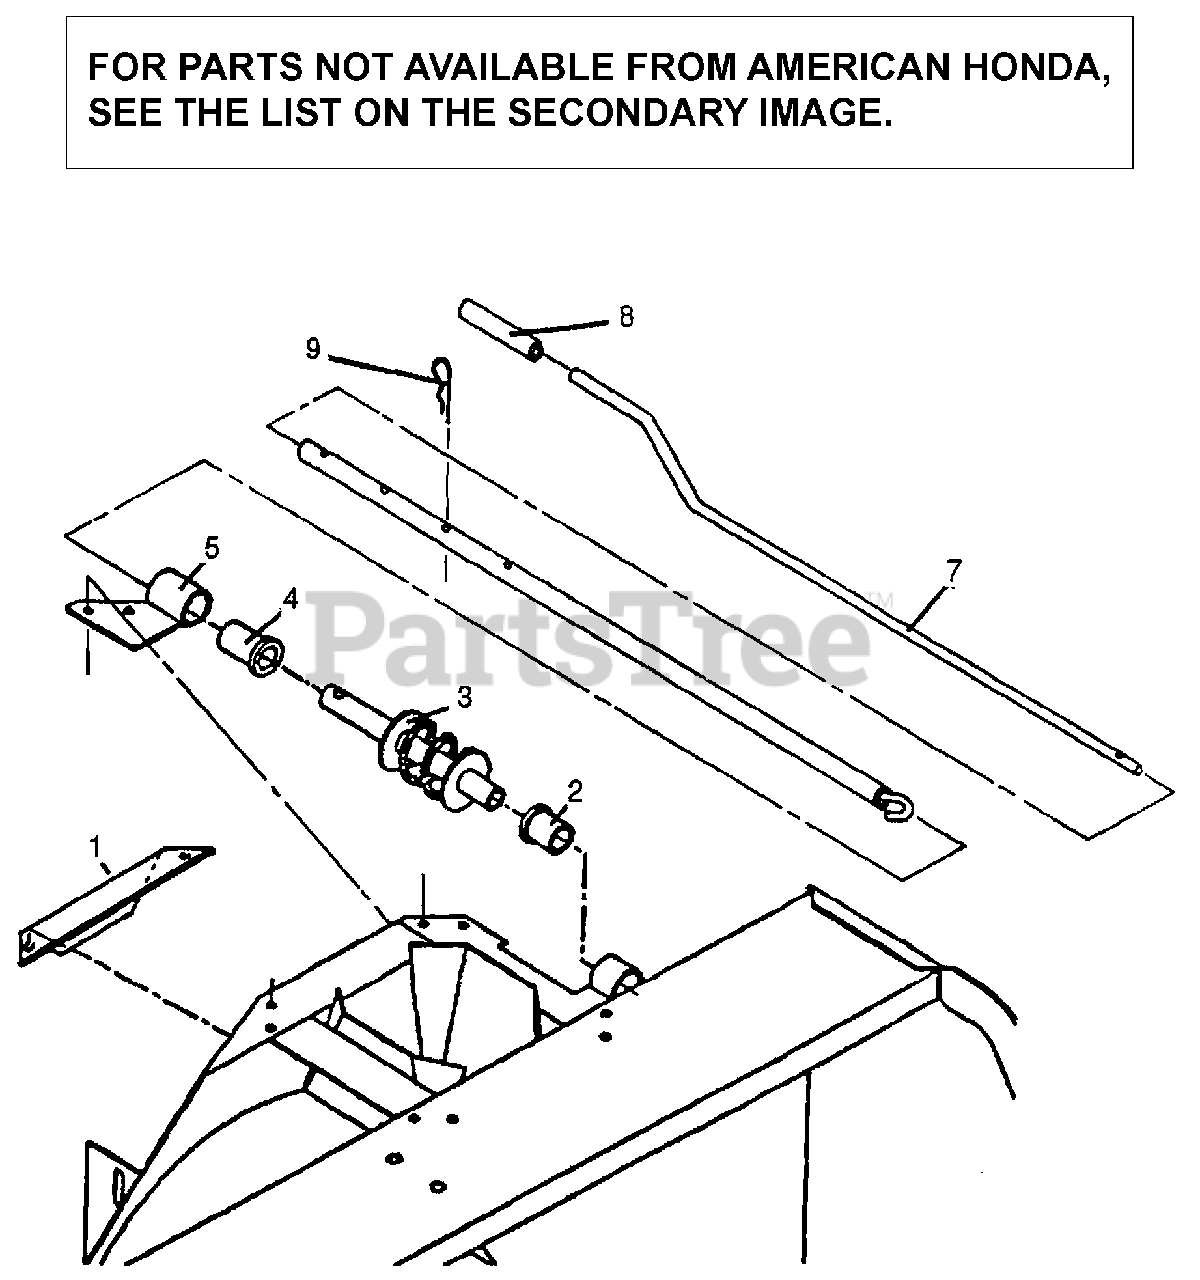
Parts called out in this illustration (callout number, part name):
2	BUSHING, PLASTIC (1-5/16")
3	WORM, ROTATION CLOCKWISE
4	BUSHING, PLASTIC (1-11/16")
5	SUPPORT, ROTATION WORM
6	TUBE, ROTATION (UPPER)
8	GRIP
